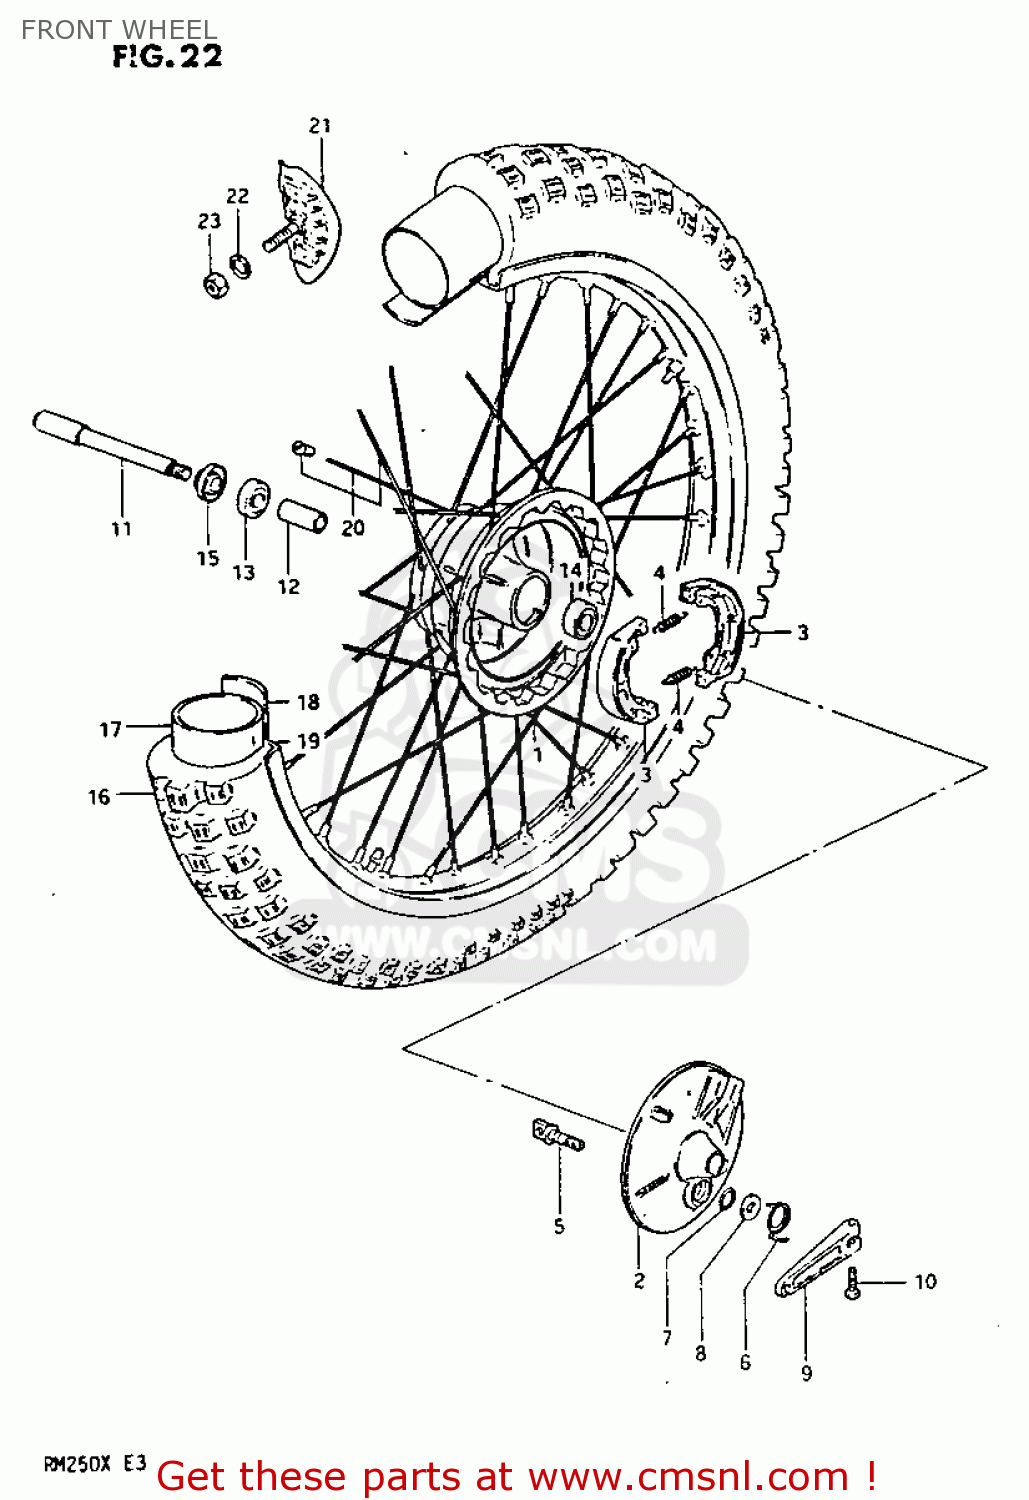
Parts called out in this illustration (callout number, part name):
1	HUB,FRONT
2	PANEL,FRONT HUB
3	SHOE,BRAKE
4	SPRING
5	CAM,FRONT BRAKE
6	SPRING
7	O RING(D:2.5,ID:11.4)
8	WASHER(12.5X20X1)
9	LEVER,FRONT BRAKE CAM
10	BOLT
11	AXLE,FRONT
12	SPACER,FRONT HUB BEARING
13	BEARING
14	BEARING
15	SPACER,FRONT AXLE,RIGHT
16	TIRE,FRONT
17	TUBE
18	PROTECTOR,WHEEL,INNER
19	RIM,FRONT WHEEL (1.60X21)
20	SPOKE SET,FRONT
21	STOPPER,BEAD
22	WASHER
23	NUT
